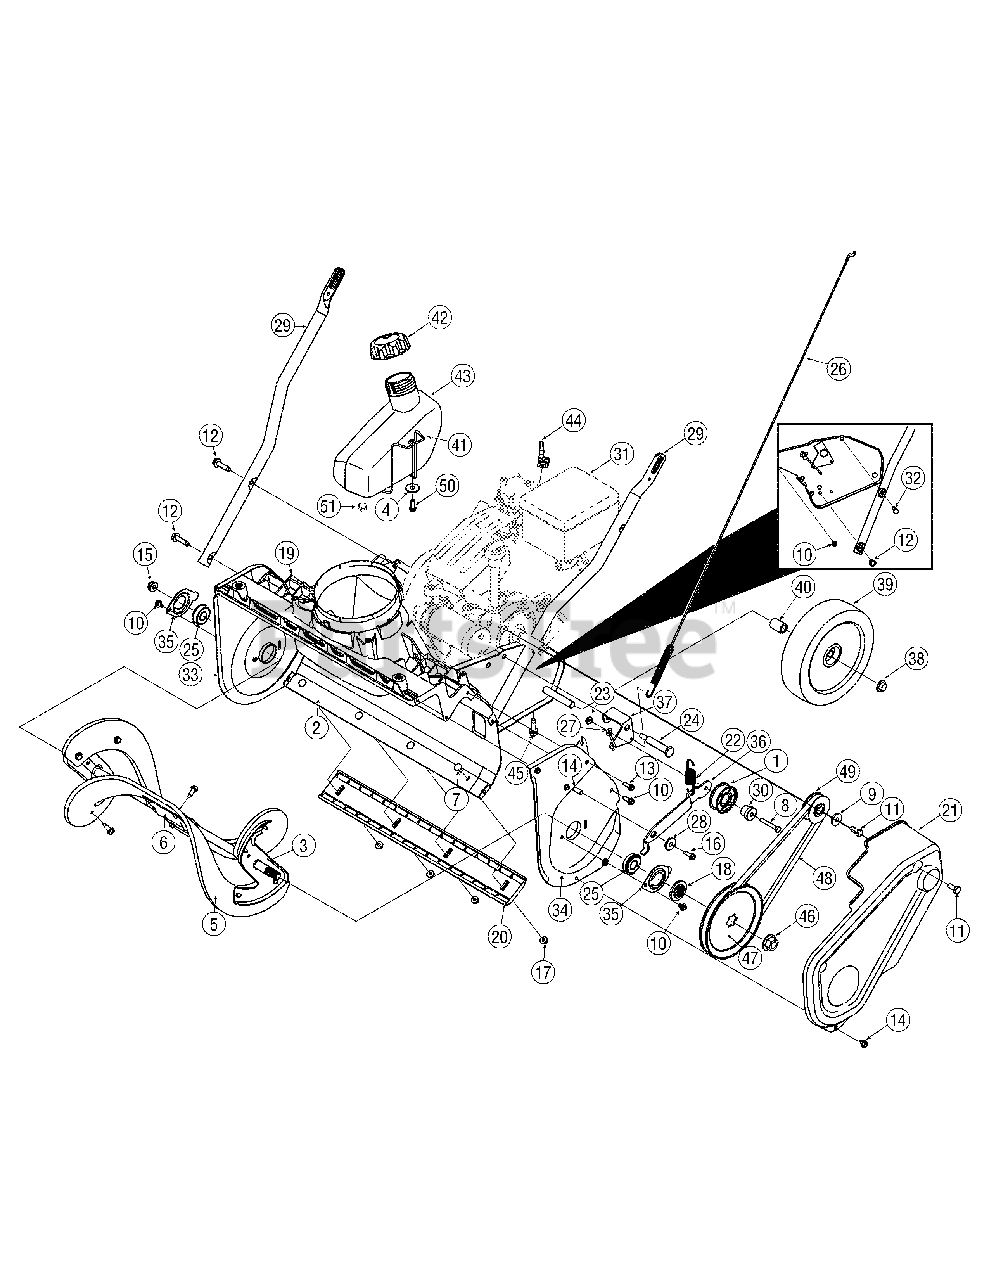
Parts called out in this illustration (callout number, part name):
1	Idler Pulley Assembly
2	Frame
3	Auger Assembly Complete
3	Auger Assembly Axle w/o paddles and center auger bracket
4	Flat Washer, .265 x 1.000 x .030
5	Auger Replacement Kit
6	Center Auger Bracket
6	Hex Washer Screw 1/4-20 x.750
7	Carriage Screw, 1/4-20 x .62
8	Hex Washer Screw, 1/4-20 x 1.500
9	Flat Washer, .330 x 1.250 x .120
10	Hex Washer Screw, 1/4-20 x .625
11	Hex Lock Screw, 5/16-24 x .750
12	Hex Washer Screw, 5/16-18 x 1.250
13	Hex Washer Screw, 1/4-15 x .750
14	Hex Washer Screw, 1/4-20 x .500
15	Flange Lock Nut, 3/8-16
16	Hex Washer Screw, 5/16-18 x .750
17	Flange Lock Nut, 1/4-20
18	Pulley Hub
19	Chute Adapter
20	Shave Plate
21	Belt Cover
22	Extension Spring, .70 x 3.035
23	Push Nut, .25 x .50
24	Shoulder Bolt, 5/16-24 x .496 x 2.18
25	Ball Bearing
26	Clutch Cable
27	Drive Cable Wire Support
28	Shoulder Spacer
30	Shoulder Spacer, .260 x .785 x .538
31	Replacement Engine
32	Hex Screw, 5/16-24 x 1.25
37	Cable Idler Bracket
38	Push Cap, 1/2
39	Wheel, 7"
40	Spacer, .525 x .775 x .835
41	Gas Tank Wire Support
42	Fuel Cap
43	Fuel Tank, 2 quart
44	Choke Extension Lever
45	Hex Washer Screw, 3/8-16 x 1.000
46	Flange Nut, 9/16-20
47	Pulley, 1/2 x 6.00
48	Belt, .500 x 35.06
49	Pulley Half, .625 x 2.25
50	Tri-Plask Screw, 1/4-10 x .625
51	Hose Clamp, .490
